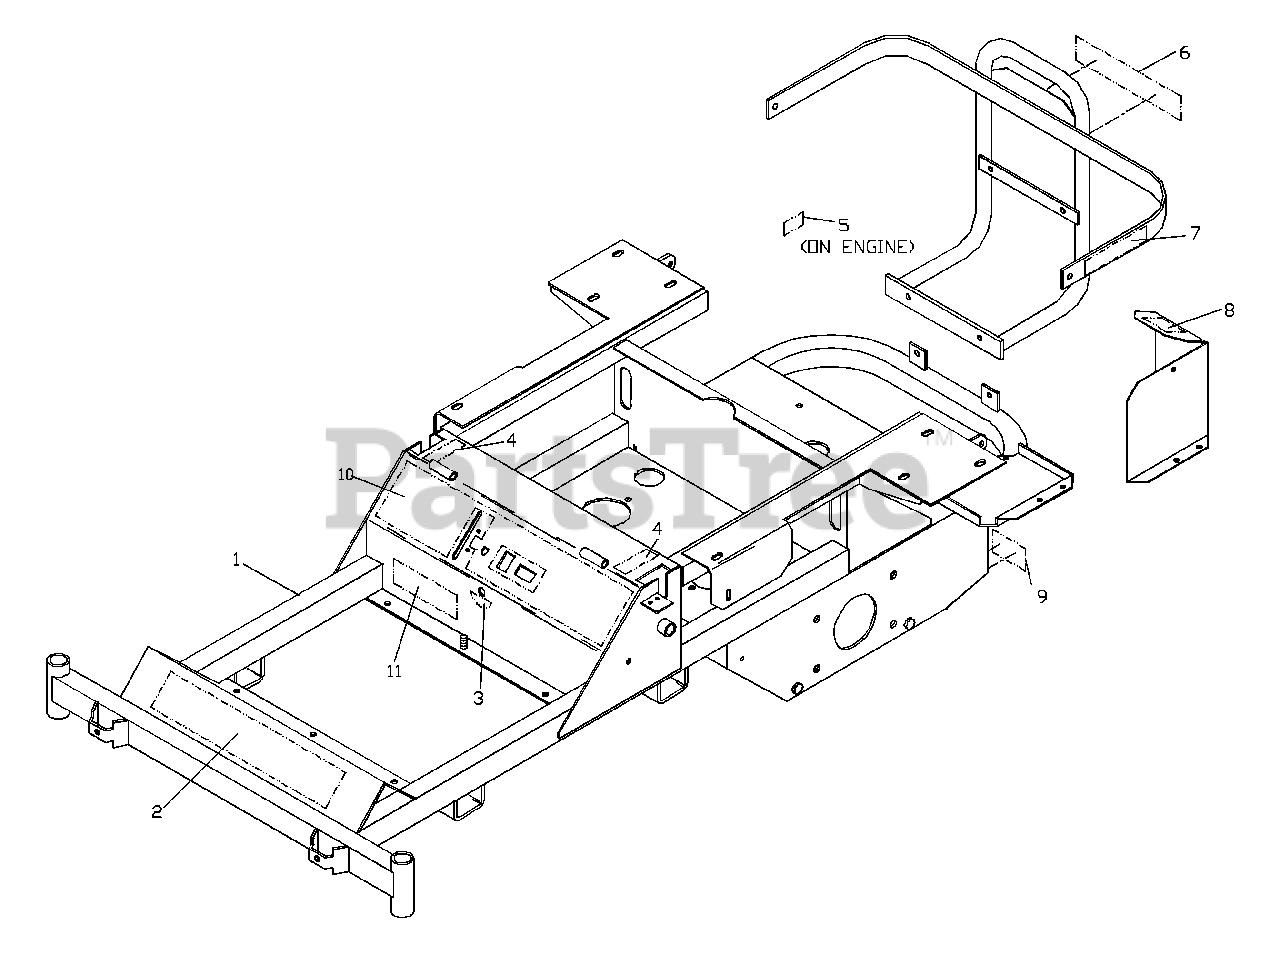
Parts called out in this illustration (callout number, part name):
1	MAIN FRAME W/DECALS
2	DECAL, HUSQVARNA
3	DECAL, FUEL VALVE
4	DECAL, MOTION CONTROL
5	DECAL, EXHAUST
6	DECAL, HUSQVARNA
7	DECAL, BATTERY
8	DECAL, PROP. 65
9	DECAL, DANGER
10	DECAL, CONSOLE
11	DECAL, NASCAR
